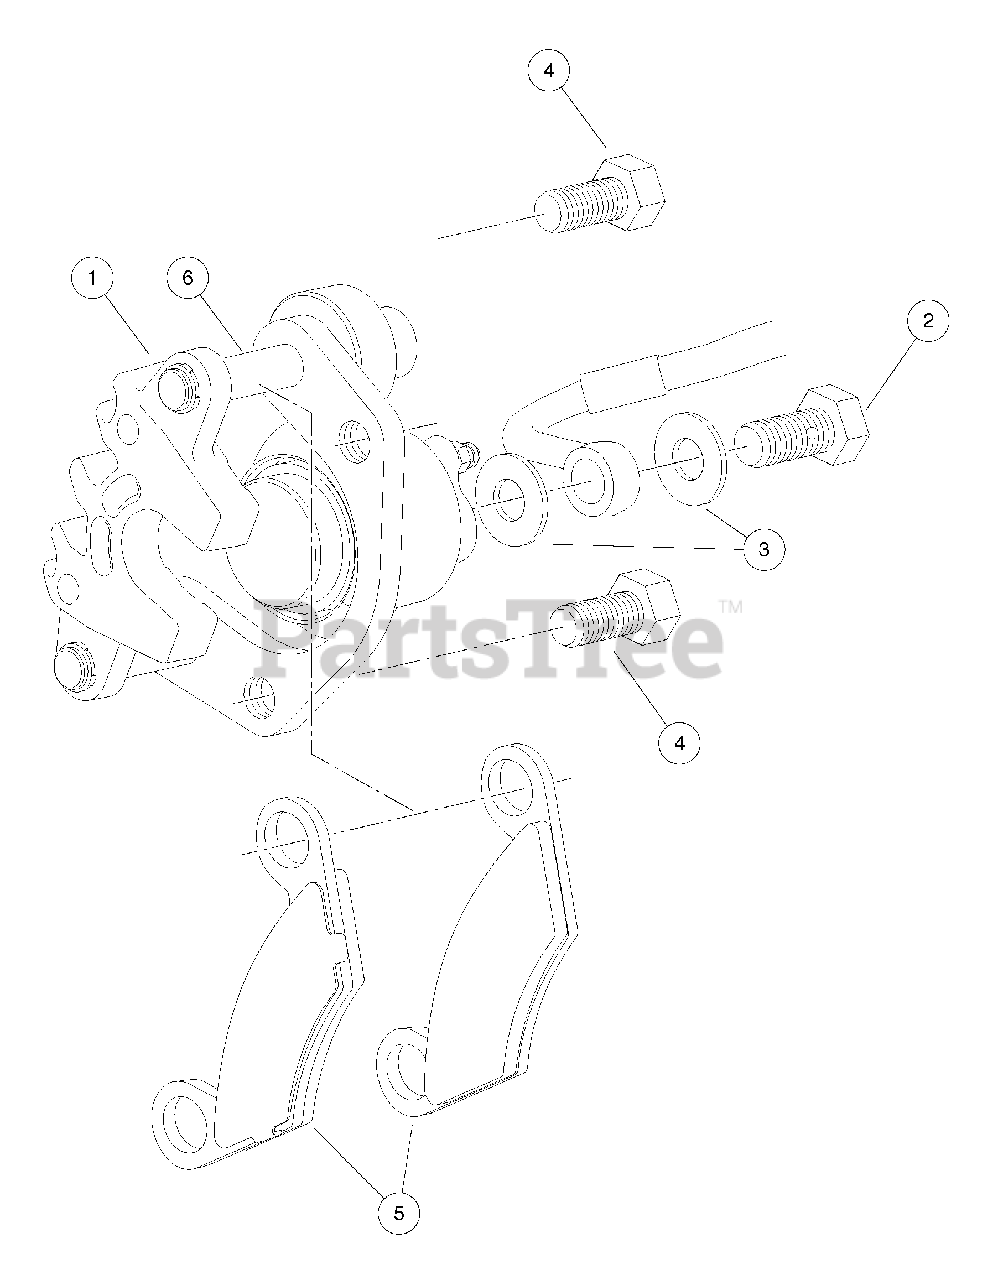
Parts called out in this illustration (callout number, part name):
1	Brake Caliper, Front, with Brake Pads
2	Bolt, Banjo, M10x1x19
3	Washer, Copper, M10 Crush
4	Bolt Flange Head, 3/8-24x.750 with Loctite
5	Service Kit, Brake Pad (4 Pads)
6	Pin, Slide, 7/16
